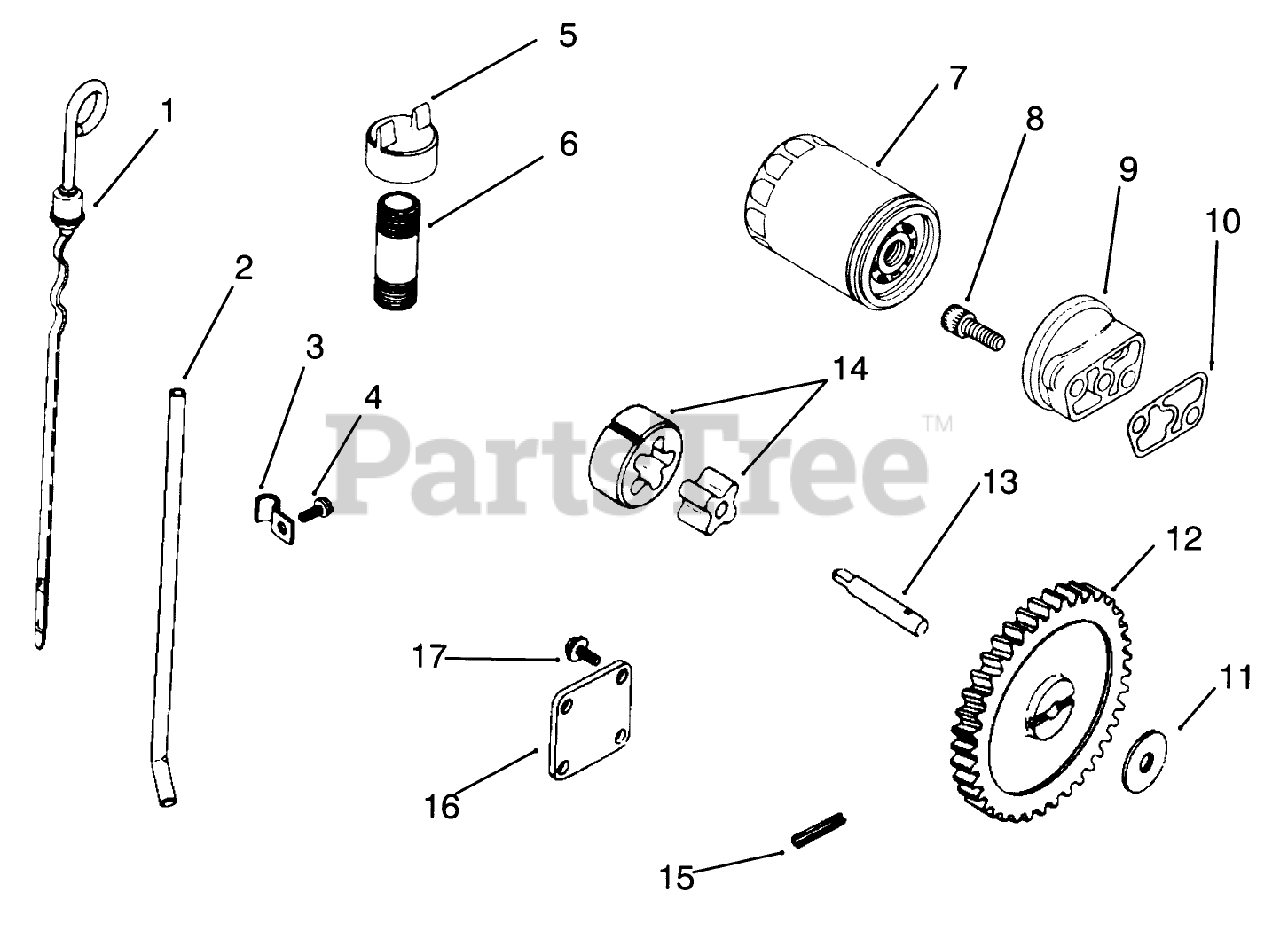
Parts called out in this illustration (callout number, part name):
1	Distick-Blade
2	Tube-Oil Level
3	Screw
4	Clip-Tube
5	Cap-Pipe
6	Pipe-Oil Fill
7	Filler-Oil
8	Screw-H.C.
9	Adapter
10	Gasket-Cover
11	Spacer-Shim
12	Gear-0il Pump
13	Shaft-0il Pump
14	Rotor Set
15	Pin-Roll
16	Cover-Oil Pump
17	Screw
